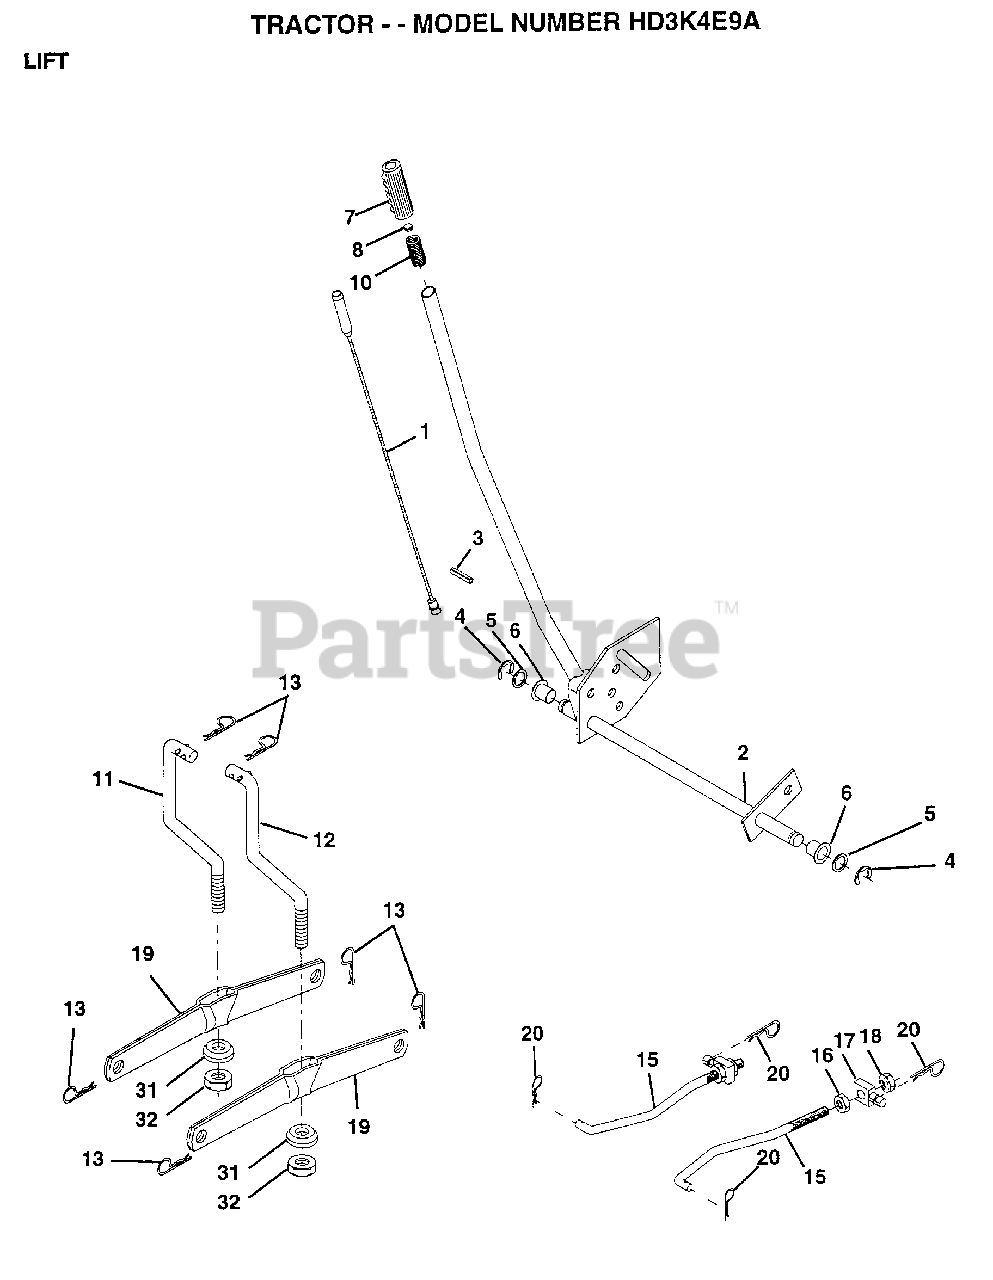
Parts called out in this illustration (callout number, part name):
1	WIRE ASM
2	HANDLE.LIFT.LH.
3	PIN GROOVE
5	WASHER
6	NYLON BEARING
7	GRIP
13	RETAINER SPRING
15	LINK.FRONT
16	NUT
17	TRUNION
18	NUT.LK.W/WSH.1/2.
19	ARM SUSP REAR
20	RETAINER.SPRING
31	BEARING PVT LH
32	NUT.CROWNLOCK.3/8
